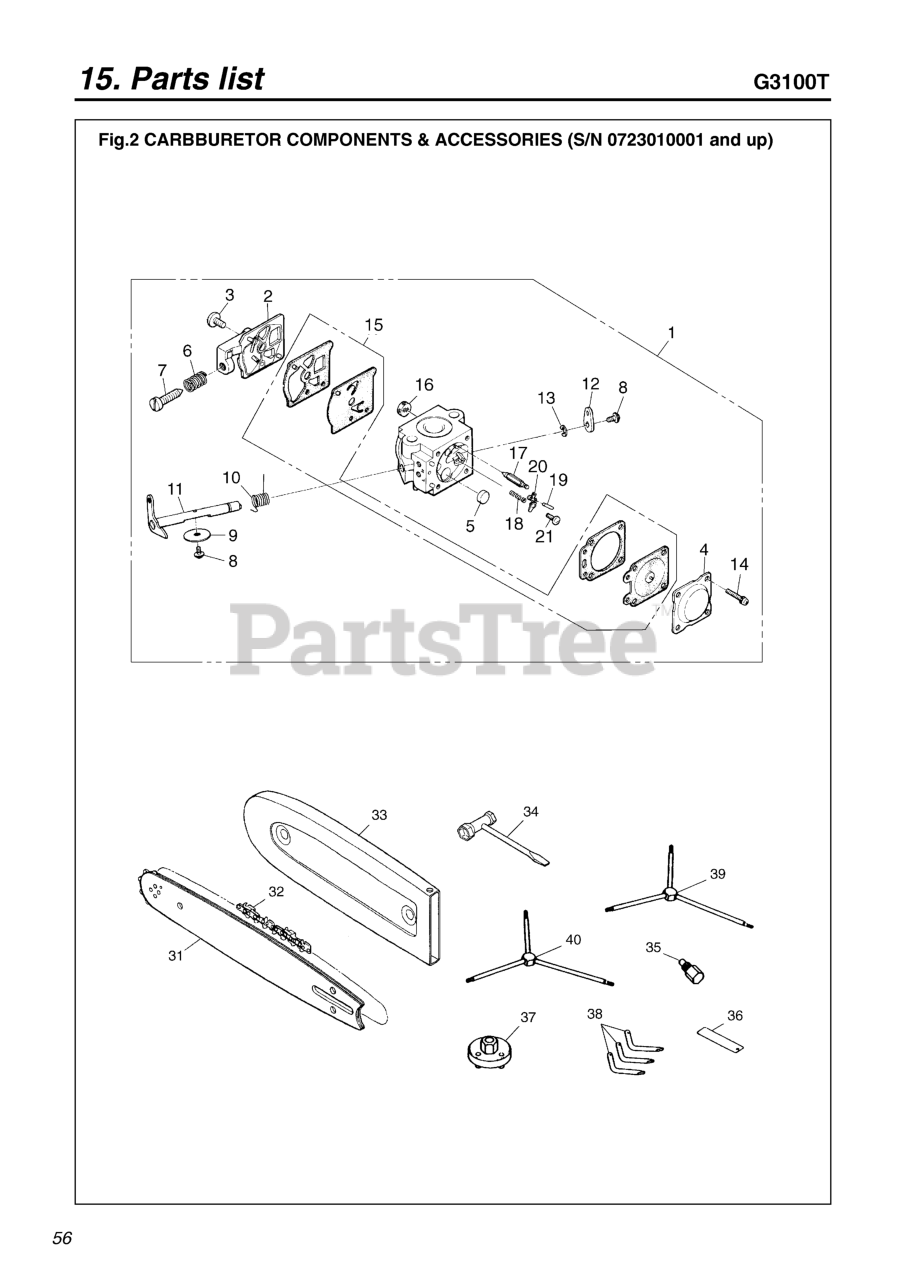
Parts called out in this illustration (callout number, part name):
1	CARBURETOR ASSY
2	PUMP COVER
5	PLUG, WELSH
6	SPRING, IDLE
8	SCREW (RPLS 3310-81360)
10	SPRING, RETURN
11	SHAFT ASSEMBLY
14	SCREW ASSEMBLY
15	GASKET KIT
15	PUMP, GASKET
15	PUMP, DIAPHRAM
15	GASKET
15	DIAPHRAGM
16	SCREEN (RPL 331081380)
17	VALVE, INLET
19	PIN, METERING LEVER
20	LEVER
31	BAR 14
33	PROTECTOR (14.5
34	WRENCH, PLUG
36	GAUGE (TOOL)
37	WRENCH (TOOL)
38	WRENCH (TOOL)
40	HEX WRENCH (TOOL)
